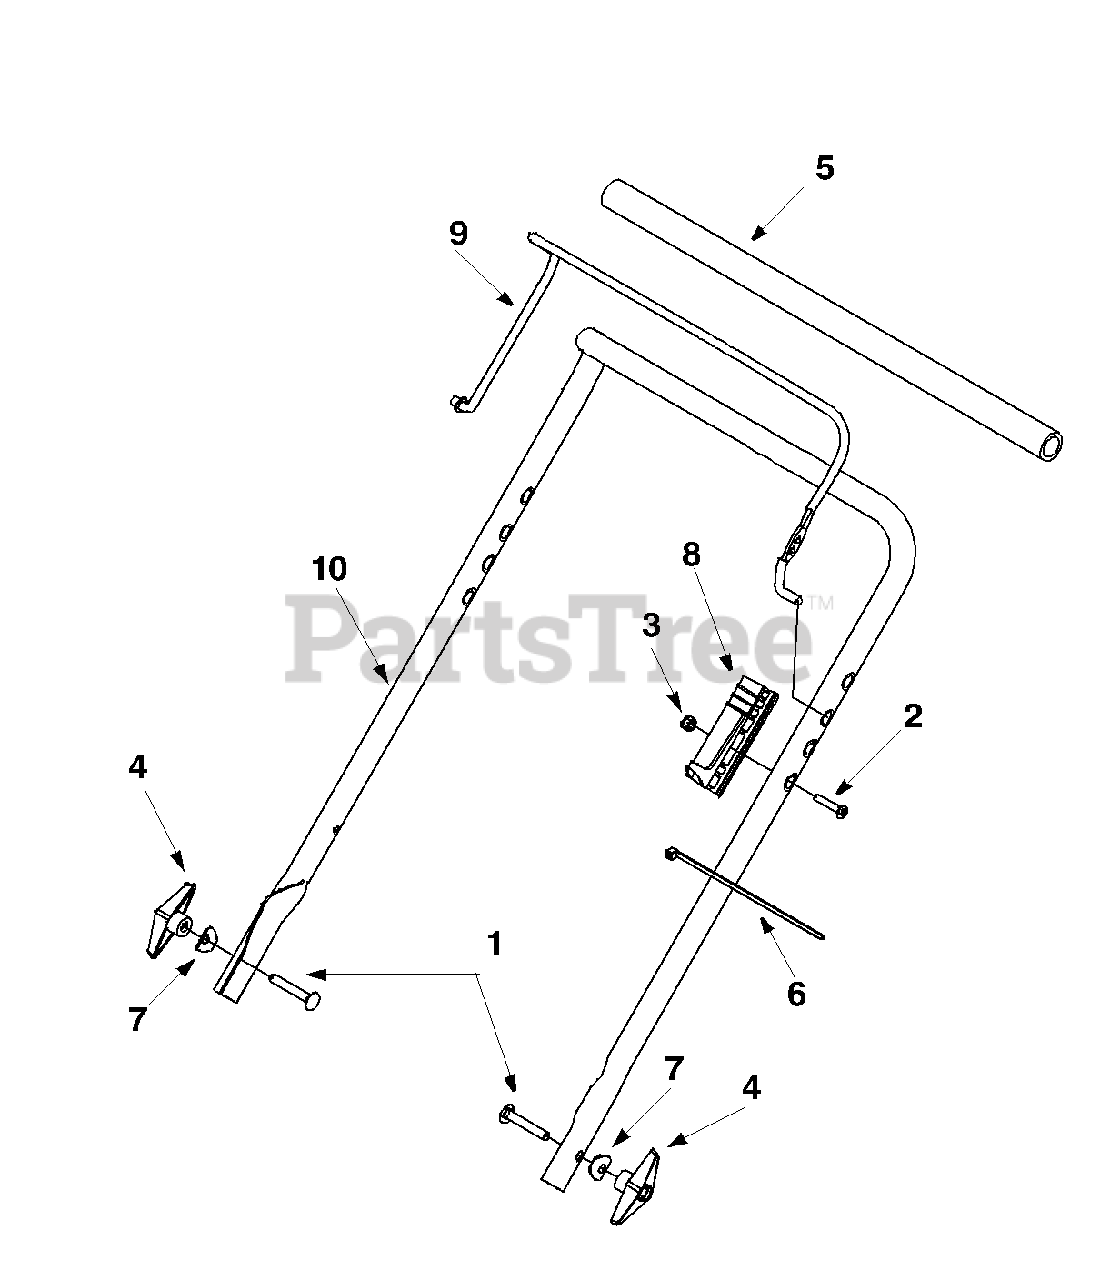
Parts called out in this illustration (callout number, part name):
1	Carriage Screw 5/16-18 x 2.0"
2	Machine Screw
3	Hex Lock Nut 1/4-20
4	Hand Knob w/ Wing Nut
5	Foam Grip
6	Cable Tie
7	Saddle Washer
8	Control Housing
